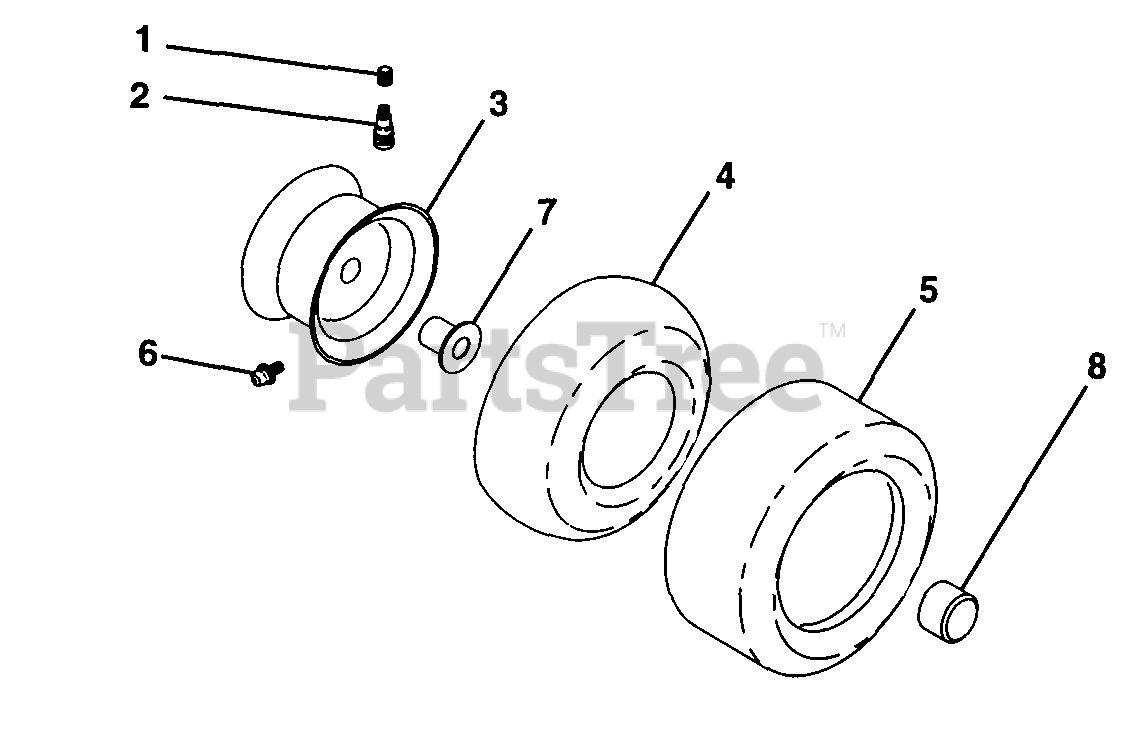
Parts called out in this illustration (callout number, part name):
1	Cap, Valve, Tire
2	Stem, Valve
3	Rim Assembly, Front
4	Tube, Front
5	Tire, Front
6	Fitting, Grease
7	Bearing, Flange (Front Wheel Only)
8	Cap, Hub, Axle Blk.
